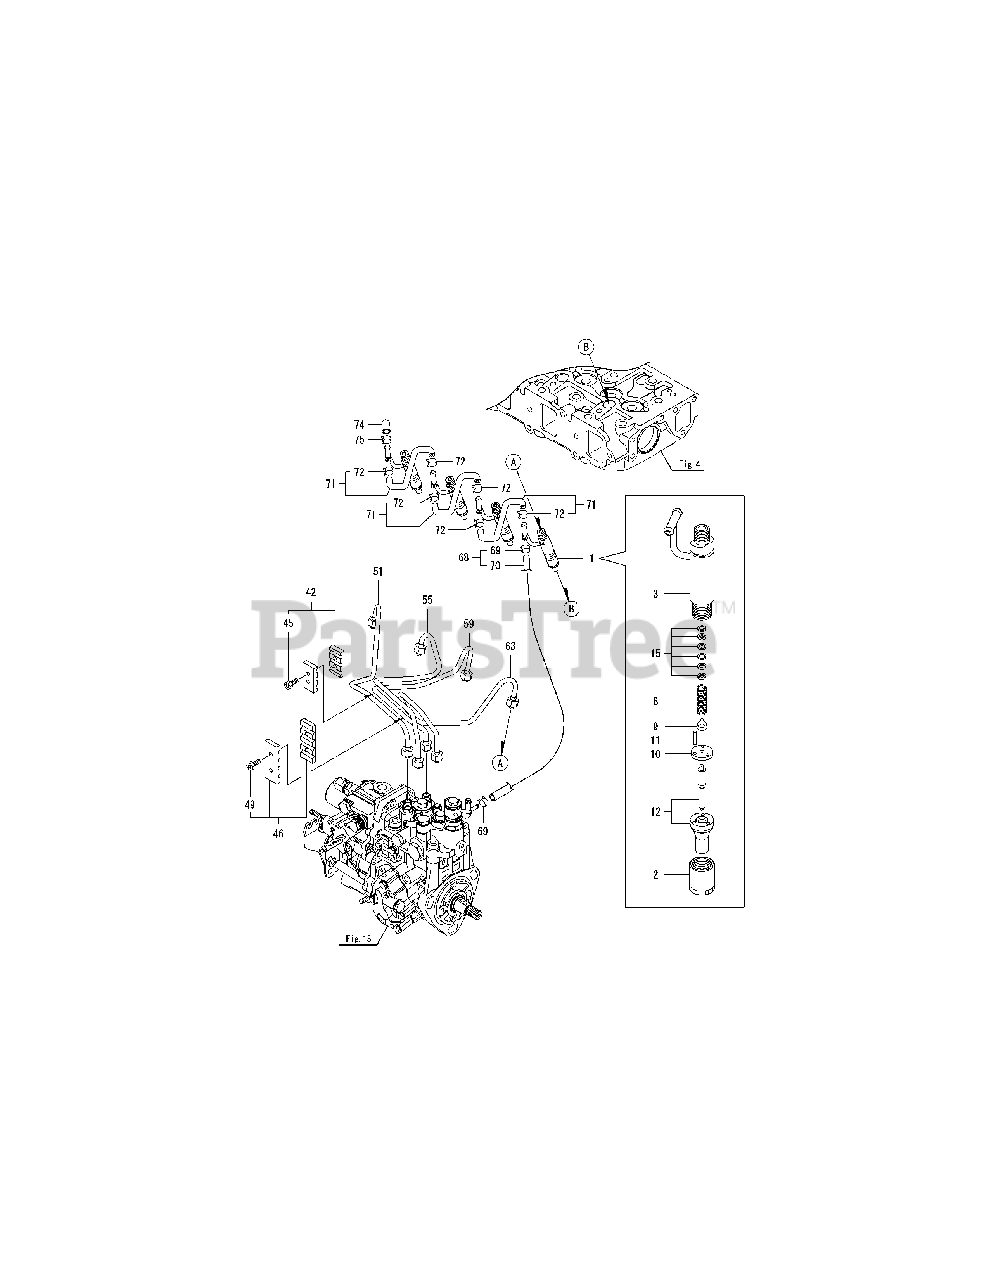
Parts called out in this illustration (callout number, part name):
1	FUEL INJECTOR(REB
3	HOLDER ASSY, NOZZLE
8	SPRING, NOZZLE
15	SHIM SET
42	RETAINER, PIPE
45	BOLT M4X14,HEX.SCKT.
46	RETAINER, PIPE
49	BOLT M4X14, HEX.SCKT.
51	PIPE ASSY, INJECTION
55	PIPE ASSY, INJECTION
59	PIPE ASSY, INJECTION
63	PIPE ASSY, INJECTION
68	PIPE ASSY, RETURN
70	PIPE, FUEL RETURN
71	PIPE ASSY, RETURN
